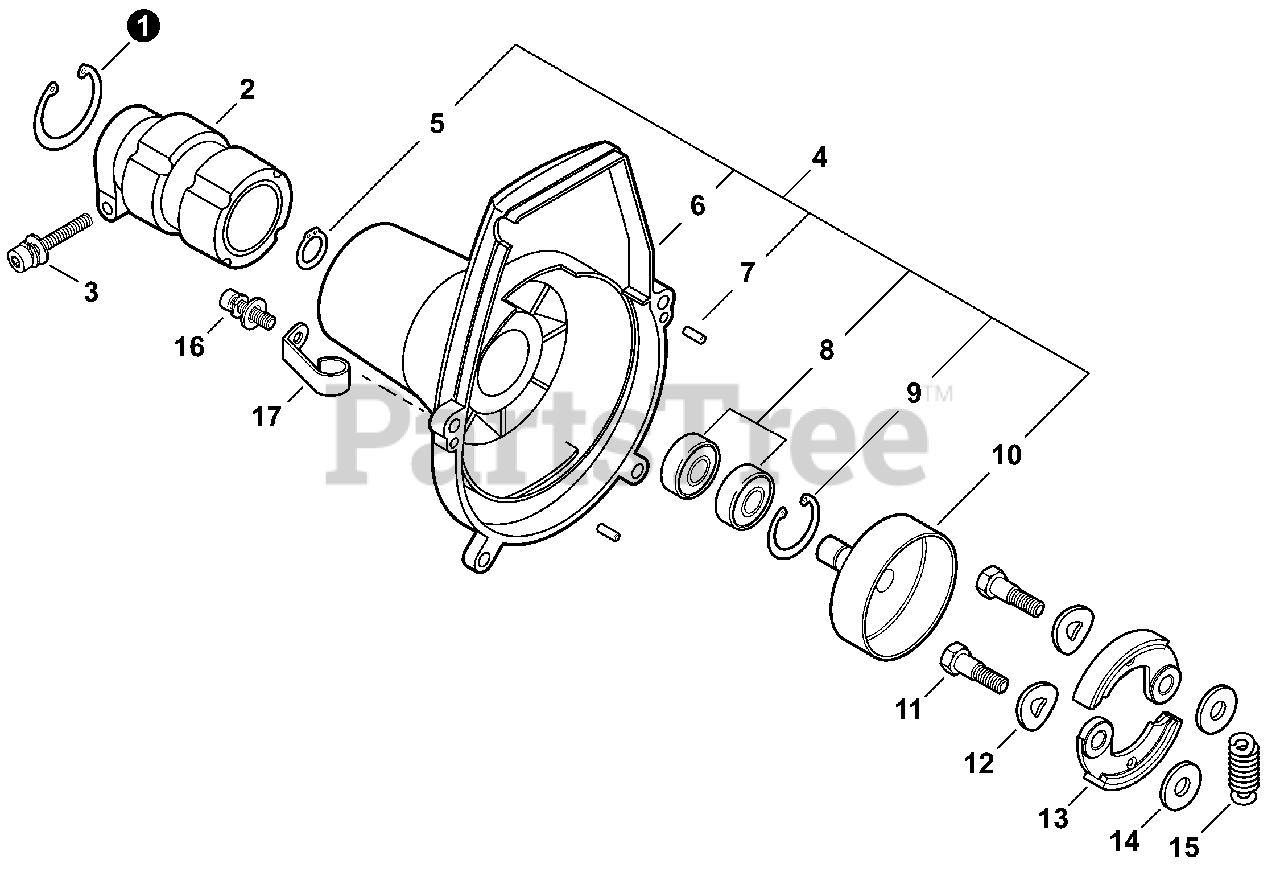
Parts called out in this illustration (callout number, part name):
1	RING, SNAP Ø42
2	HOLDER, MAIN PIPE
3	BOLT 5×28
4	COVER ASSY, FAN - ORANGE
5	RING, SNAP 12
6	COVER, FAN
7	PIN, LOCATING 4
8	BEARING, BALL 6001
9	RING, SNAP 28
10	DRUM, CLUTCH
11	BOLT, CLUTCH 8×7.9×M6
12	WASHER 8.5×16×0.5
13	SHOE, CLUTCH
14	WASHER 6.2×19×1.0
15	SPRING, CLUTCH
16	BOLT 5×18
